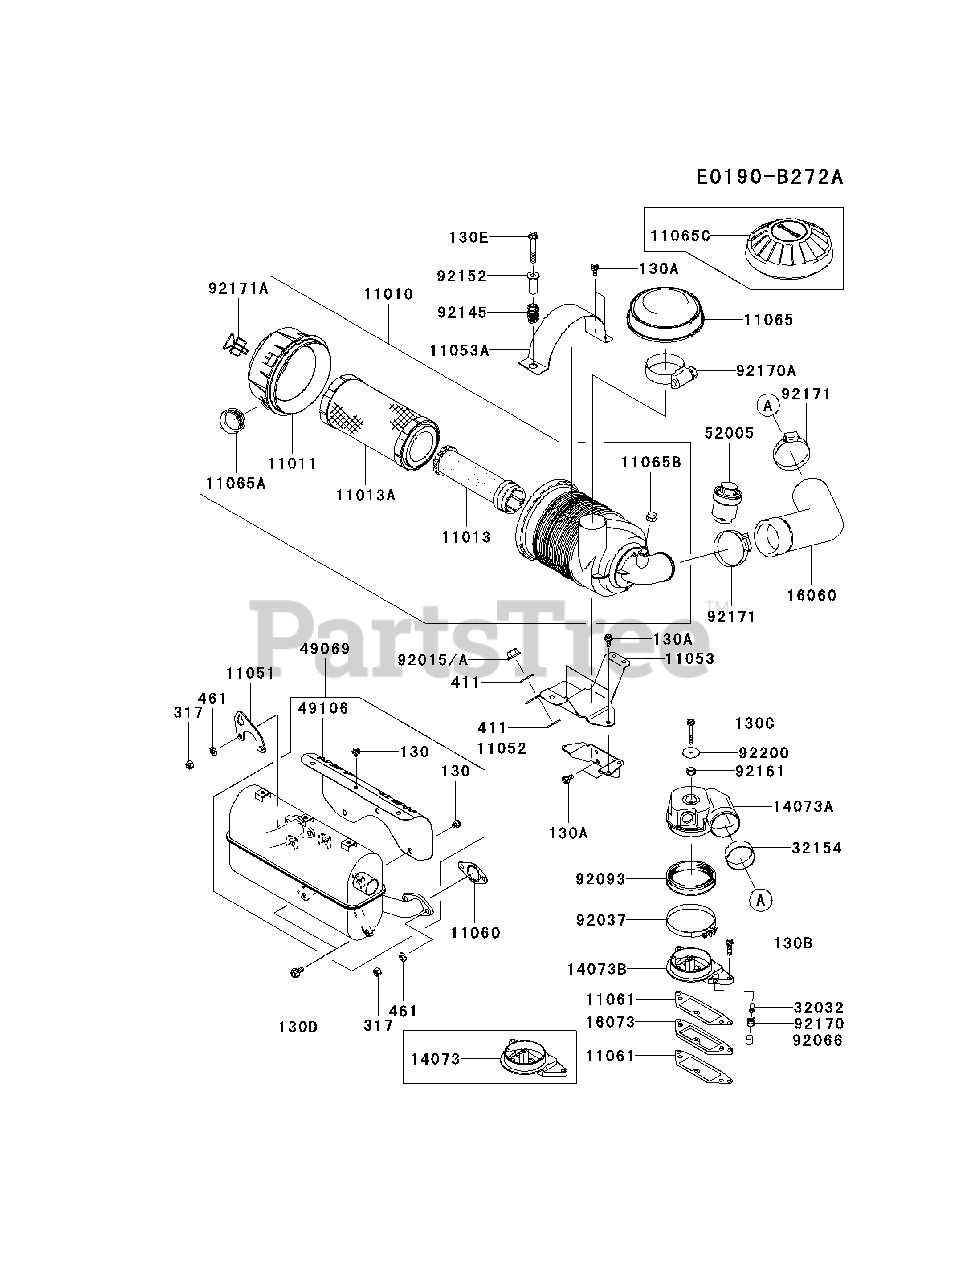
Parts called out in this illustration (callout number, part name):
130	BOLT-FLANGED,6X8
130A	BOLT-FLANGED,6X14
130B	BOLT-FLANGED,6X25
130C	BOLT-FLANGED,6X45
130D	BOLT-FLANGED,8X16
130E	BOLT-FLANGED,8X55
317	NUT-HEX-SMALL,8MM
411	WASHER-PLAIN,6MM
461	WASHER-SPRING,8MM
